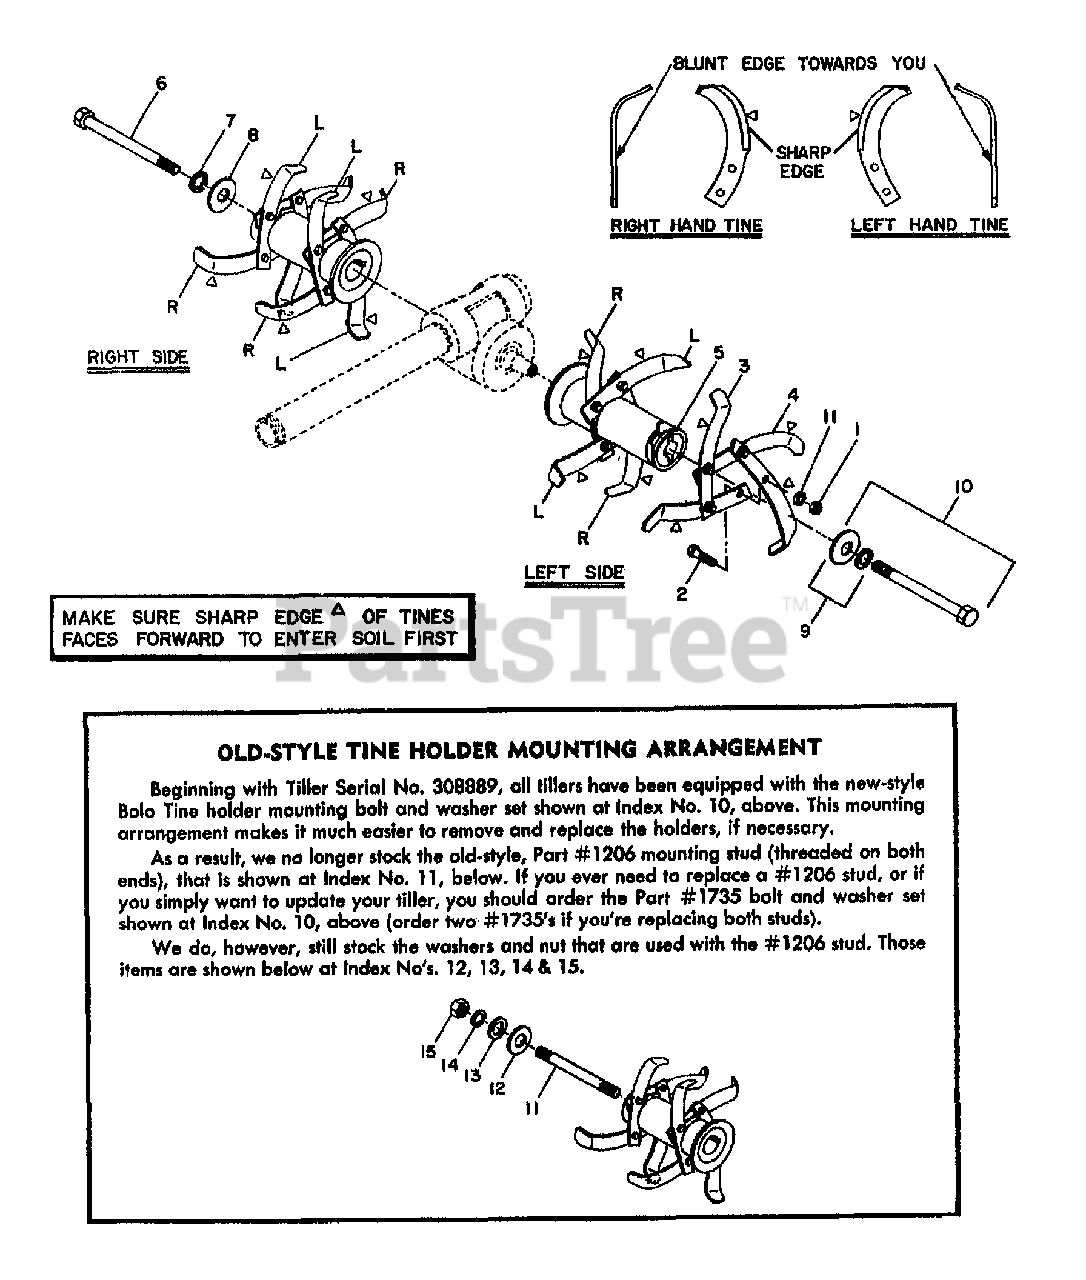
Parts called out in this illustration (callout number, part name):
1	NUT-HEX 3/8-16 ZP
2	SCR-HH 3/8-16X1.0 G5 ZP
3	TINE-BOLO RT W/HDW
4	TINE-BOLO LT W/HDW
5	HOLDER-TINE W/SHIELD
6	BOLT-HH 1/2-20 X 5.75 ZP
7	WASHER-LK .5
8	WASHER-#1.75X.531X.187 ZP
9	WASHER-SET BOLO
10	KIT-TINE BOLT & WASHER
11	WASHER-LK .375 @ DEPL
11	KIT-TINE BOLT & WASHER
12	WASHER-1.75X.625X.11
13	WASHER-PLAIN 1/2 ZP
14	WASHER-LK .5
15	NUT-HEX 1/2-20
